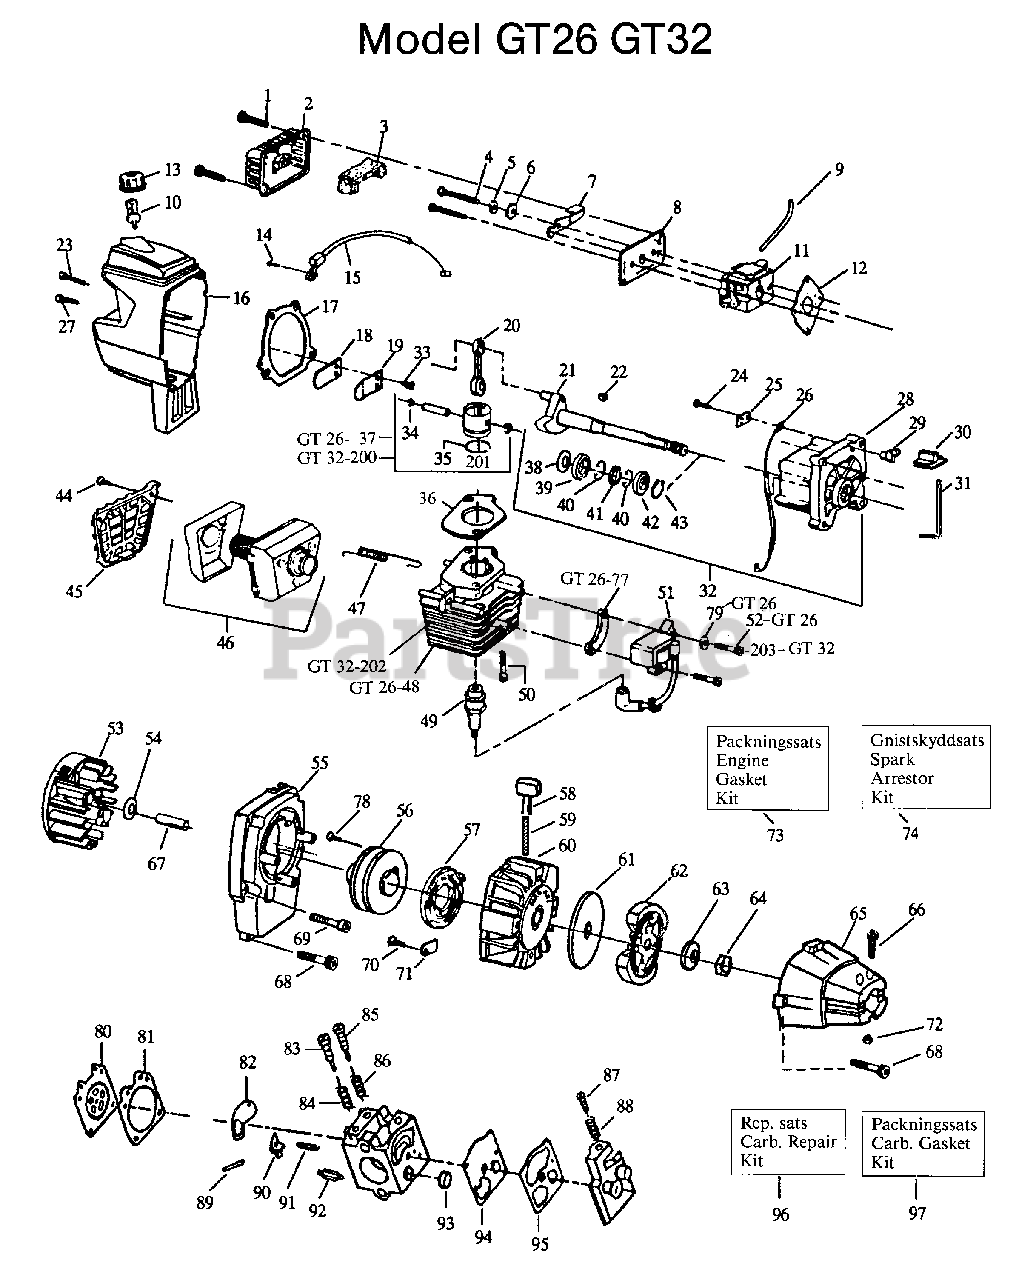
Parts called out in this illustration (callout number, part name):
1	SCREW-10-24 X 13/16
3	AIR FILTER
5	SPACER-CHOKE
7	SHUTTER-CHOKE
8	PLATE-AIR FILTER MTG.
10	ASSY-FUEL PICK-UP
11	CARBURETOR (WA-199)
12	GASKET-CARBURETOR
13	ASSY-FUEL CAP W/RETAINER
14	SCREW 8-16 X 9/16 (PLAS
17	GASKET-C'CASE/SHROUD
18	VALVE-REED
19	REED STOP
20	ASS'Y-CONNECTING ROD
21	ASSY-CRANKSHAFT
22	KEY-FLYWHEEL
23	SCREW-10-24 X 1" (TAP.)
25	INSULATOR-KILL SWITCH
26	LEAD WIRE-KILL SWITCH
27	SCREW 1/4-20 X 7/8 (TAP
28	ASSY-CRANKCASE
29	KILL SWITCH RAMP
32	ASSY-C'CASE & C'SHAFT
33	SCREW-6-19X5/16PLAST PA
34	WRIST PIN RET.
35	RING-PISTON (26.2CC)
36	GASKET-CYL W/ADHESIVE
37	KIT-PISTON (26.2CC)
38	SPACER-BEARING
39	BEARING-R8 (INNER)
40	RING-RETAINING
41	SEAL-CRANKSHAFT
42	BEARING-R8 (OUTER)
43	RING-RETAINING (SHAFT)
44	SCREW-10-16X9/16SLTD.PH
45	GUARD-MUFFLER
46	KIT-MUFFLER
47	SPRING
48	CYLINDER (26CC) (SERVIC
49	SPARK PLUG (RCJ-8) NLA
50	SCREW-1/4-20 X 13/16
51	MODULE-IGNITION
52	SCREW 8-32 X 1-9/32
53	ASSY-FLYWHEEL
54	WASHER
55	HOUSING
56	KIT-STARTER PULLEY
57	SPRING-STARTER
58	HANDLE-STARTER
61	WASHER-CLUTCH
62	KIT-CLUTCH ASS'Y
63	WASHER-BELLEVILLE
65	CLUTCH COVER
66	SCREW-10-24 X 1-3/8 (UN
67	SPACER-CLUTCH
68	SCREW-10-16 X 1-3/8 PLA
69	SCREW-10-24X1-3/8-TAPTI
70	SCREW-10-16 X 1/2 HI-LO
72	LOCKNUT-HEX 10-24
73	KIT-GASKET
74	KIT-W/E SPARK ARRESTER
77	SPACER-IGNITION MODULE
78	SCREW-6-19X9/32 PAN/SEM
80	METERING DIAPHRAGM
81	GASKET-METER DIAP
84	PRESSURE SPRING
85	NEEDLE - IDLE
87	SCREW-IDLE SPEED
89	FULCRUM PIN
92	VALVE/INLET.
93	SCREEN-DUTCH TWILL INLE
94	PUMP DIAPHRAGM
96	REPAIR PARTS KIT
97	KIT-KWIK REPAIR
200	KIT-PISTON (32CC)
201	RING-PISTON (HOOKED)
202	CYLINDER
203	SCREW-COIL MTG
